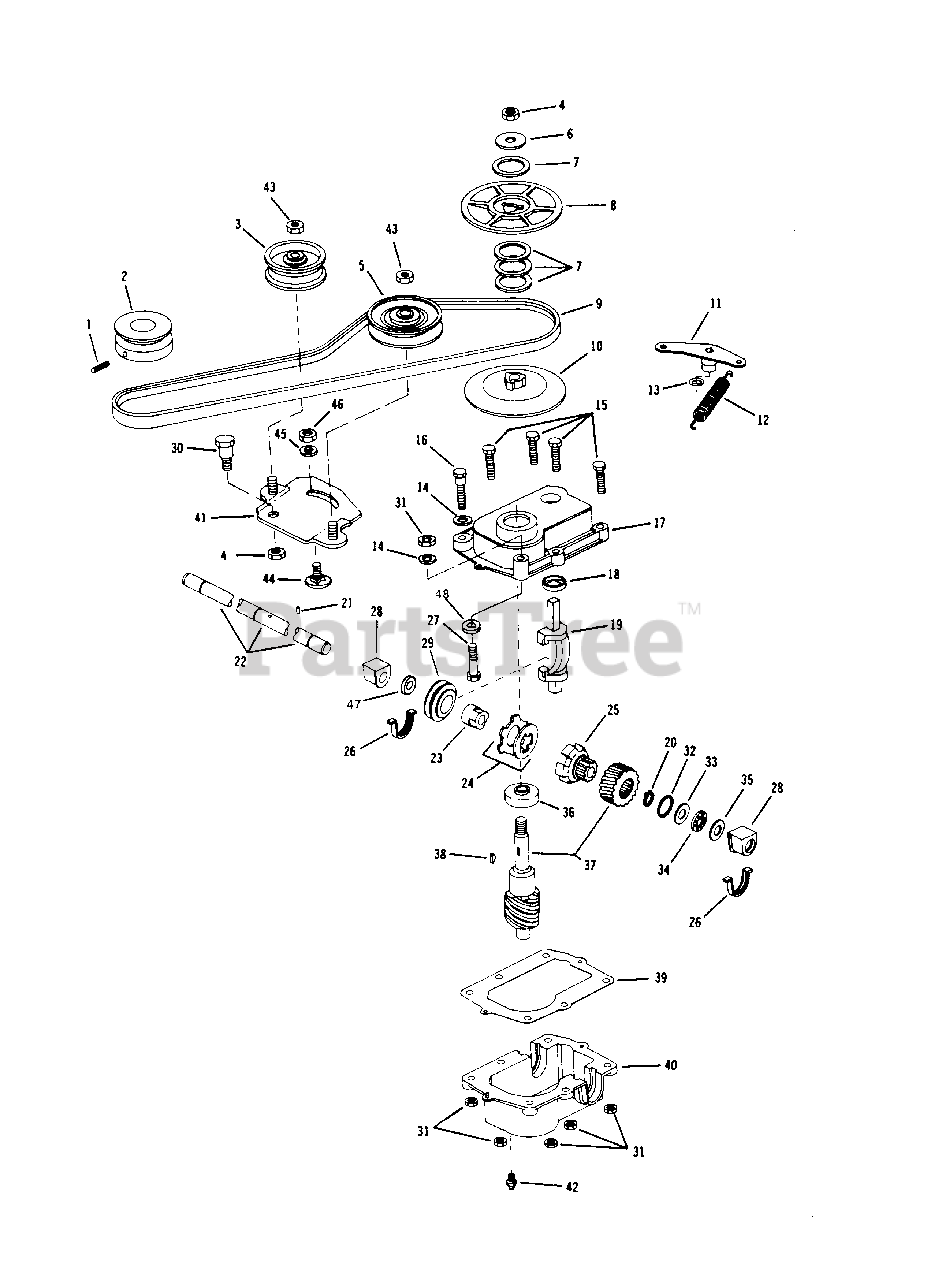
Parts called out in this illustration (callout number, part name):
1	Set Screw
2	Pulley-Engine
3	Pulley-Idler Variable Speed
4	Nut
5	Idler-V-Belt
6	Washer
7	Washer
8	Pulley Half-Upper
9	V-Belt
10	Pulley Half-Lower
11	Shift Arm
12	Spring-Extension
13	O-Ring
14	Washer
15	Screw-Hex Head-Cap
16	Bolt-Shoulder
17	Gear Case-Upper
18	Seal Guide
19	Fork-Shift
20	Ring-Retaining
21	Pin
22	Driveshaft
23	Driven Sleeve
24	Disc Clutch Kit
25	Driver
26	Packing
27	Screw
28	Bearing-Gearcase
29	Collar
30	Bolt-Shoulder
31	Nut
32	Washer-Thrust
33	Washer-Thrust
34	Bearing-Thrust
35	Washer-Thrust
36	Bearing
37	Worm Wheel and Shaft Assembly
38	Key
39	Gasket
40	Gear Case-Lower
41	Idler Plate
42	Lubrication Fitting
43	Nut-Thin
44	Bolt-Square Neck
45	Washer
46	Nut
47	Washer
48	Lockwasher
